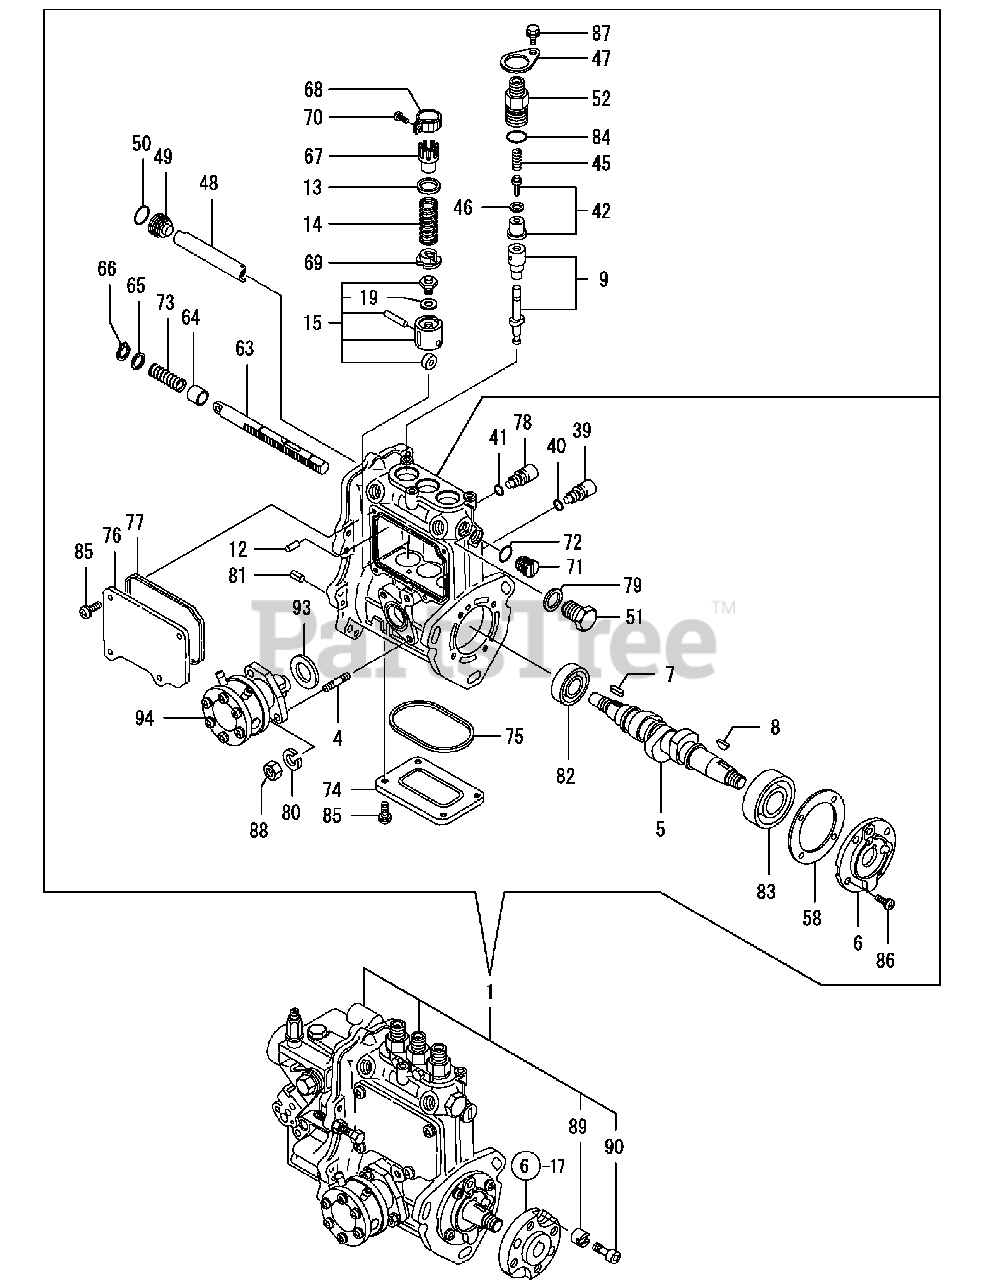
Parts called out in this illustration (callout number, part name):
4	Stud, Feed Pump
6	Support, Bearing
9	Plunger Assembly
12	Pin, Barrel Locking
14	Spring, Plunger
15	Tappet Assembly
42	Valve Assembly, Delivery
45	Spring, Delivery
46	Gasket, Delivery
52	Valve Assembly, Delivery
58	Shim Set, Adjusting
65	Spacer, Aux. Spring
67	Pinion, Control
68	Pinion
69	Receiver, Spring
76	Cover, Body Side
81	Spring Pin, 5 x 10
85	Screw, M 5 x 12
86	Screw, M 6 x 16
87	Bolt, M 5 x 10 Plated
89	Collar, FIC Fix
90	Bolt, Fixation
94	Feed Pump Assembly
